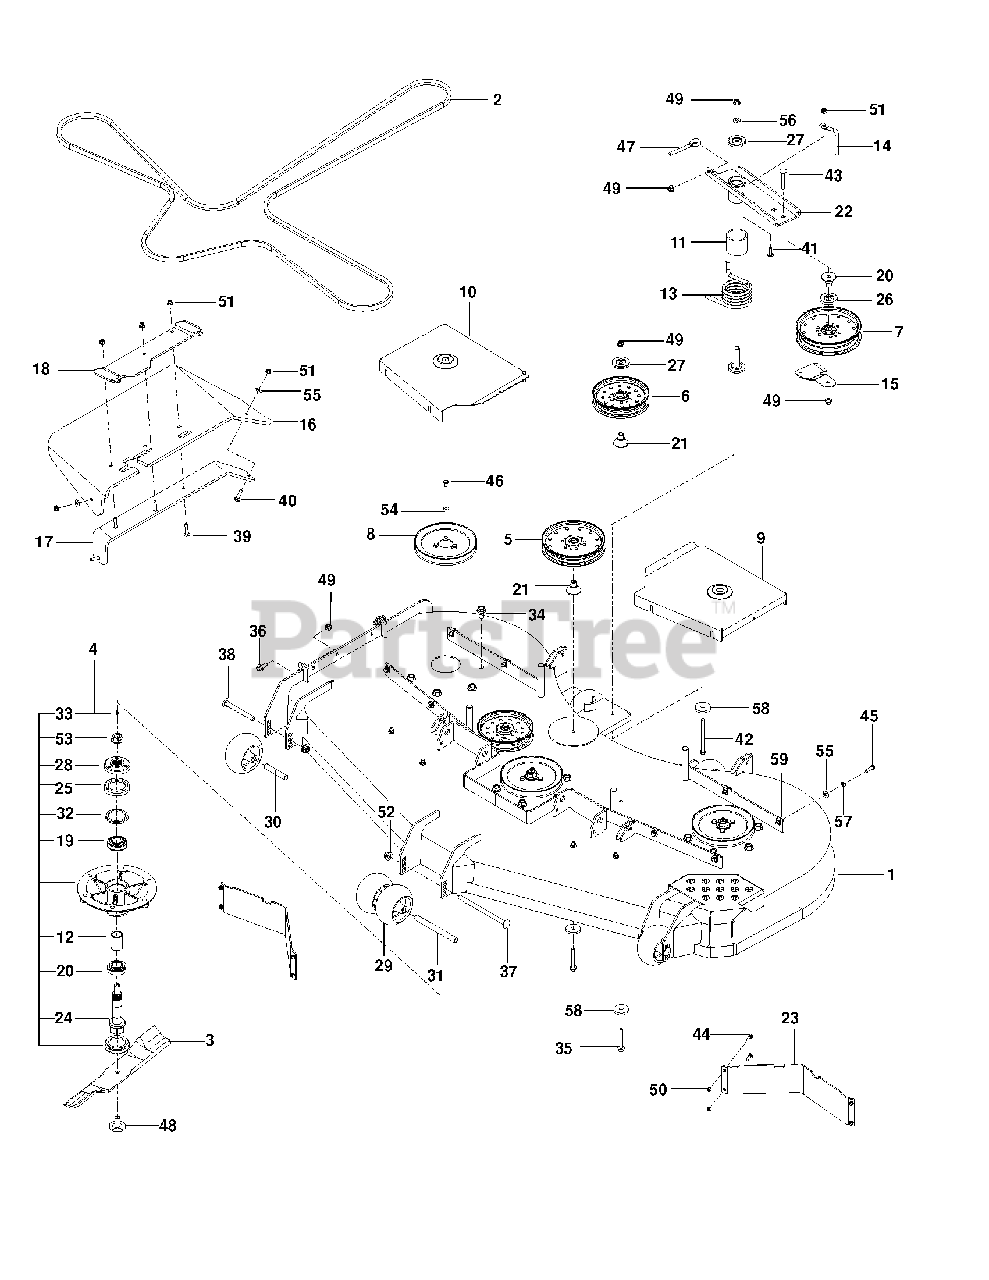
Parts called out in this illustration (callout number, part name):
1	DECK W/SAFETY DECALS 72"
2	BELT, "B", 201
4	SPINDLE ASM. 10"
5	PULLEY - 7" NARROW
6	PULLEY IDLER, 6" NARROW
7	PULLEY - IDLER 7"
9	SHIELD, 72 RT
10	SHIELD BELT LH 72 BLUE
12	SPACER - BEARING
15	BELT GUIDE, BLK
16	CHUTE, DISCHARGE 60-72
17	BRKT - CHUTE SUPPORT BLACK
18	BRKT - CHUTE MTG BLACK
19	BEARING - 206KRR8
20	BEARING, IDLER ARM
21	BEARING, IDLER PIVOT
24	SHAFT - SPINDLE
25	CUP - DEBRIS
26	SHIELD, DUST
27	DUST SHIELD
28	HUB - PULLEY
29	ROLLER, GAUGE .635 BORN
30	TUBE, ROLLER AXLE
31	TUBE, ROLLER AXLE LONG
32	V-RING, 55MM
33	ZERK
35	HHFS 3/8-16 X 2 3/4
36	HHFS 3/8-16 X 1 GRD 5 ZD
37	RHSNB 1/2-13 X 8 GR5 ZD
38	RHSNB 1/2-13 X 4.75 GR5 ZD
39	RHSNB 5/16-18 X 1-1/2 GR 5 ZD
40	BOLT, CARRIAGE 5/16X1-1/4
41	RHSSNB 5/16C X 1.0
42	HCS 3/8-16 X 4-1/2 GR 8 ZD
43	CARRIAGE BOLT 3/8-16 X
45	HCS 5/16C X 1
46	HCS 5/16-18 X 1/2 GR 5 ZD
48	BLADE BOLT/WASHER
49	NUT 3/8-16 HEX FLG NYLOC ZD
50	NUT 1/4-20 NYLOC
51	5/16-18 NYLOC FLANGE NUT
52	NUT, 1/2-13 HEX FLG NYLOC ZD
53	NUT FLANGE 3/4-16
54	WASH 5/16 DISC SPRING ZD
55	WASHER 5/16 FLAT
56	WASHER, 3/8 THICK
57	WASHER 5/16 LOCK
58	SPINDLE WASHER
59	U-CLIP 5/16-18 NUT RETAINER
